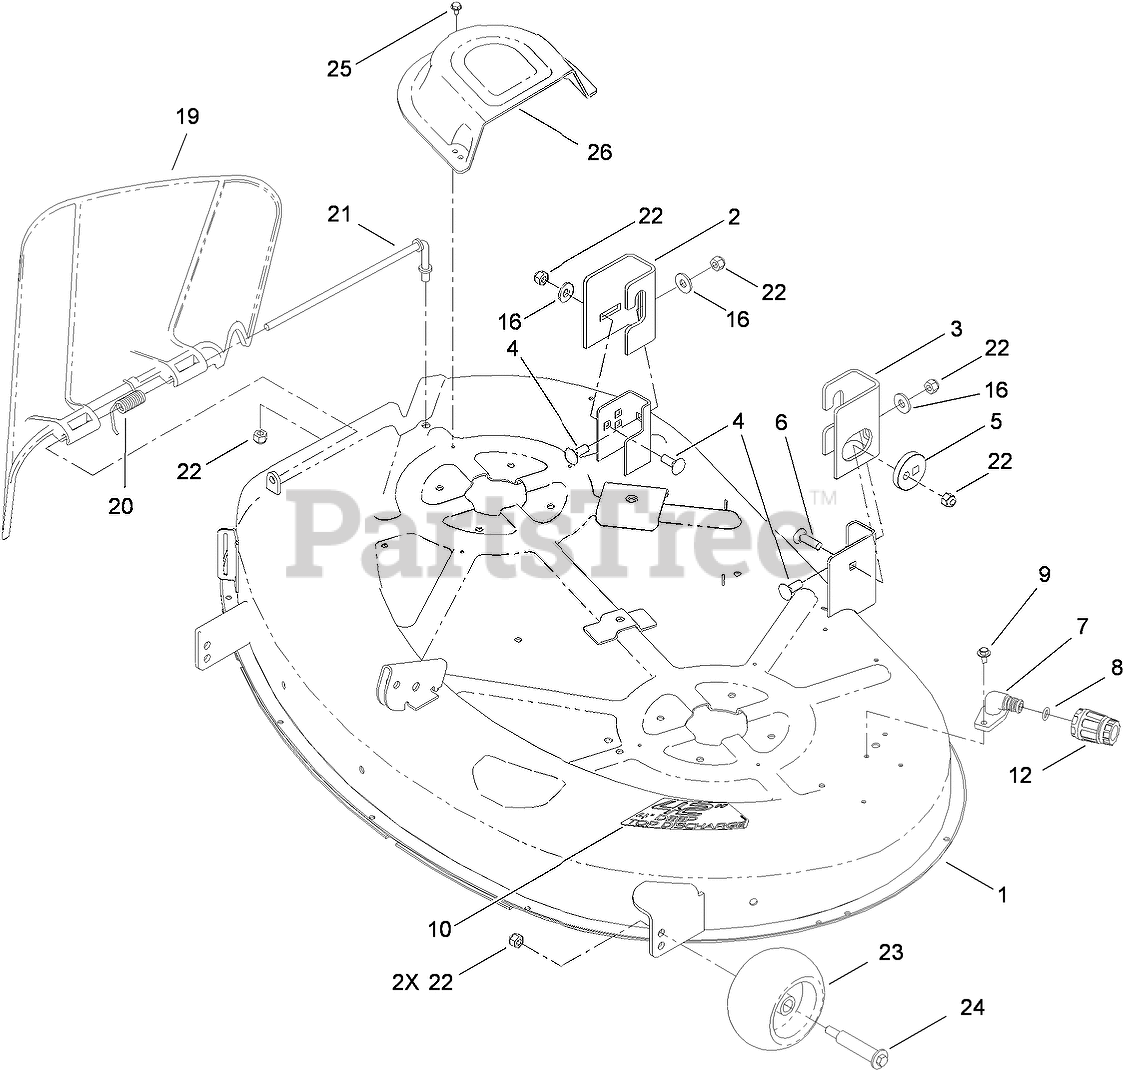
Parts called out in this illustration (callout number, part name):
1	42 INCH DECK AND DECAL ASM
2	BRACKET-HANGER, RIGHT REAR
3	BRACKET-HANGER, LEFT REAR
4	BOLT-CARR
5	ECCENTRIC
6	SCREW-CARR
7	FITTING-WASHOUT
8	O-RING
9	SCREW-HHFTF
12	CONNECTOR-HOSE
16	WASHER-HARDENED
19	DEFLECTOR
20	SPRING-TORSION
21	ROD-PIVOT
22	NUT-LOCK, NI
23	ROLLER-SCALP, ANTI
24	BOLT-SHOULDER
25	SCREW-HWHTF
26	COVER-BELT
